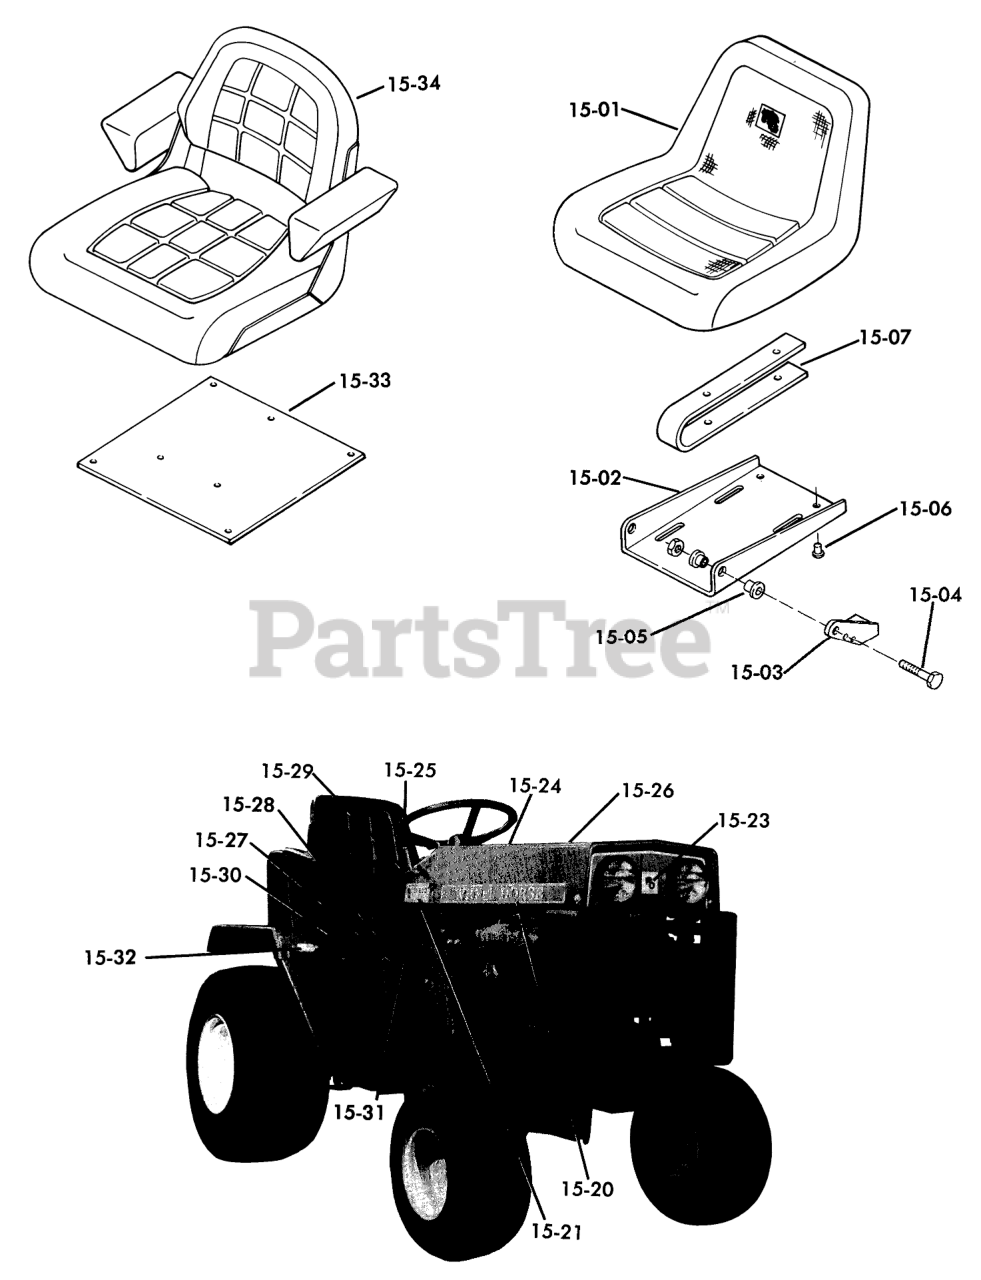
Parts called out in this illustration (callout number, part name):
15-06	BUMPER-RUBBER
15-07	Hairpin Cotter
15-21	Decal-"D-160 Automatic"
15-21	Decal-"D-200 Automatic"
15-28	Decal-Caution
15-29	Decal
